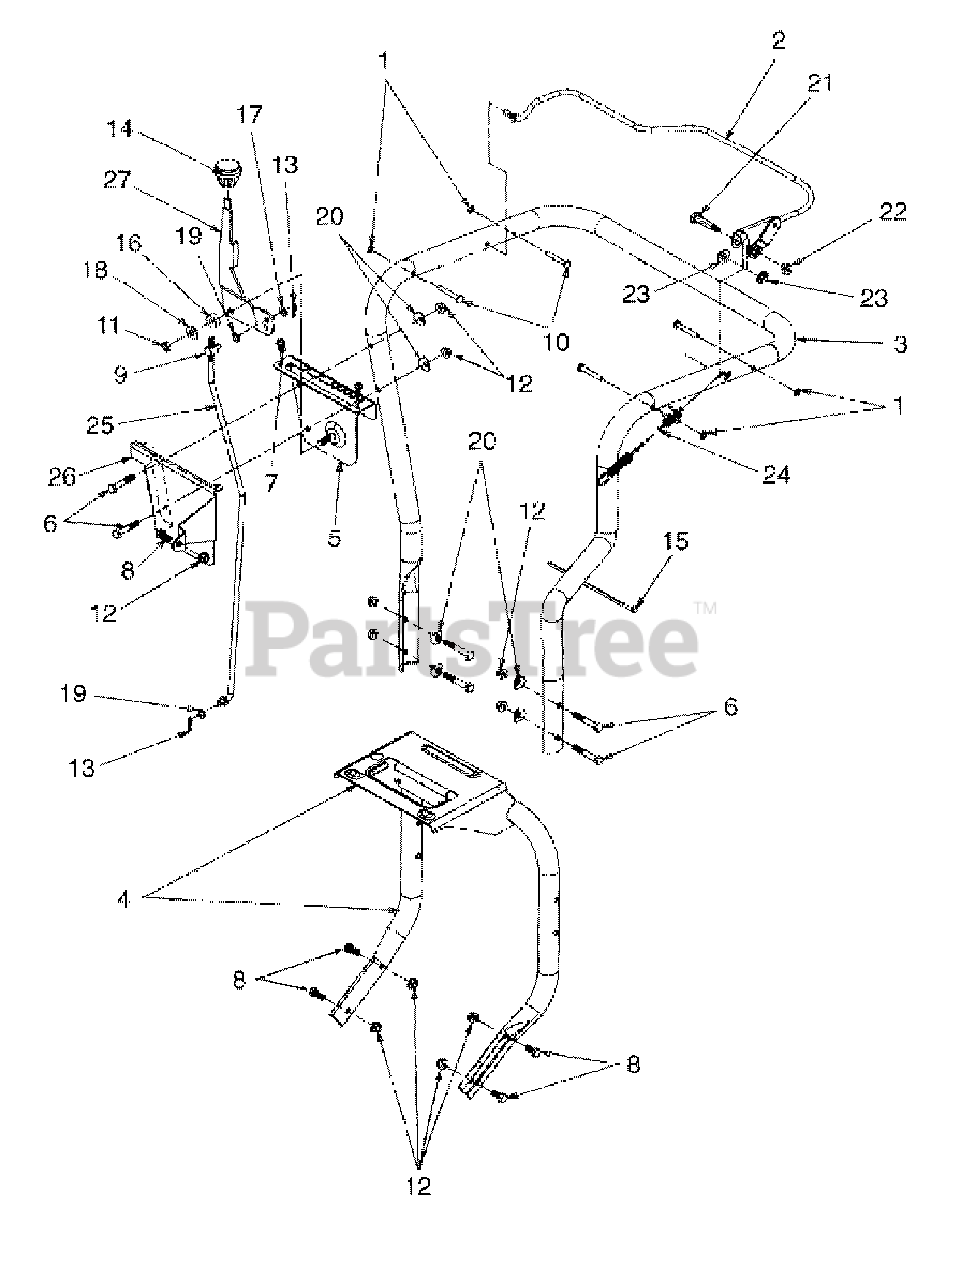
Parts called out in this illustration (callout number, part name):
1	Nut, Push, .25
2	Control Assembly, Clutch
3	Handle Assembly, Upper
4	Handle Assembly, Lower
5	Bracket Assembly, Shift
6	Screw, Hex Cap, 5/16-18 x 2.0
7	Screw,Hex Wash Hd, 4-14 x .625
8	Screw, Hex Cap 5/16-18 x .75
9	Ferrule
10	Pin, Stud, .250 x 1.75
11	Nut, Hex Insert Jam Lock 3/8-24
12	Nut, Hex Flange Lock 5/16-18
13	Pin, Internal Cotter
14	Knob, Shift
15	Cable Tie
16	Washer, Rubber
17	Washer, Flat, .385 x .62 x .06
18	Washer, Flat, .406 x .875 x .059
19	Washer, Spring, .390 x .62
20	Washer, Saddle, .320 x .93
21	Shoulder Screw, .374 x 1.375
22	Shoulder Nut, 1/4-20
23	Bearing, Hex Plastic Flange
24	Cable, Clutch
25	Rod, Shift
26	Cover, Shift
